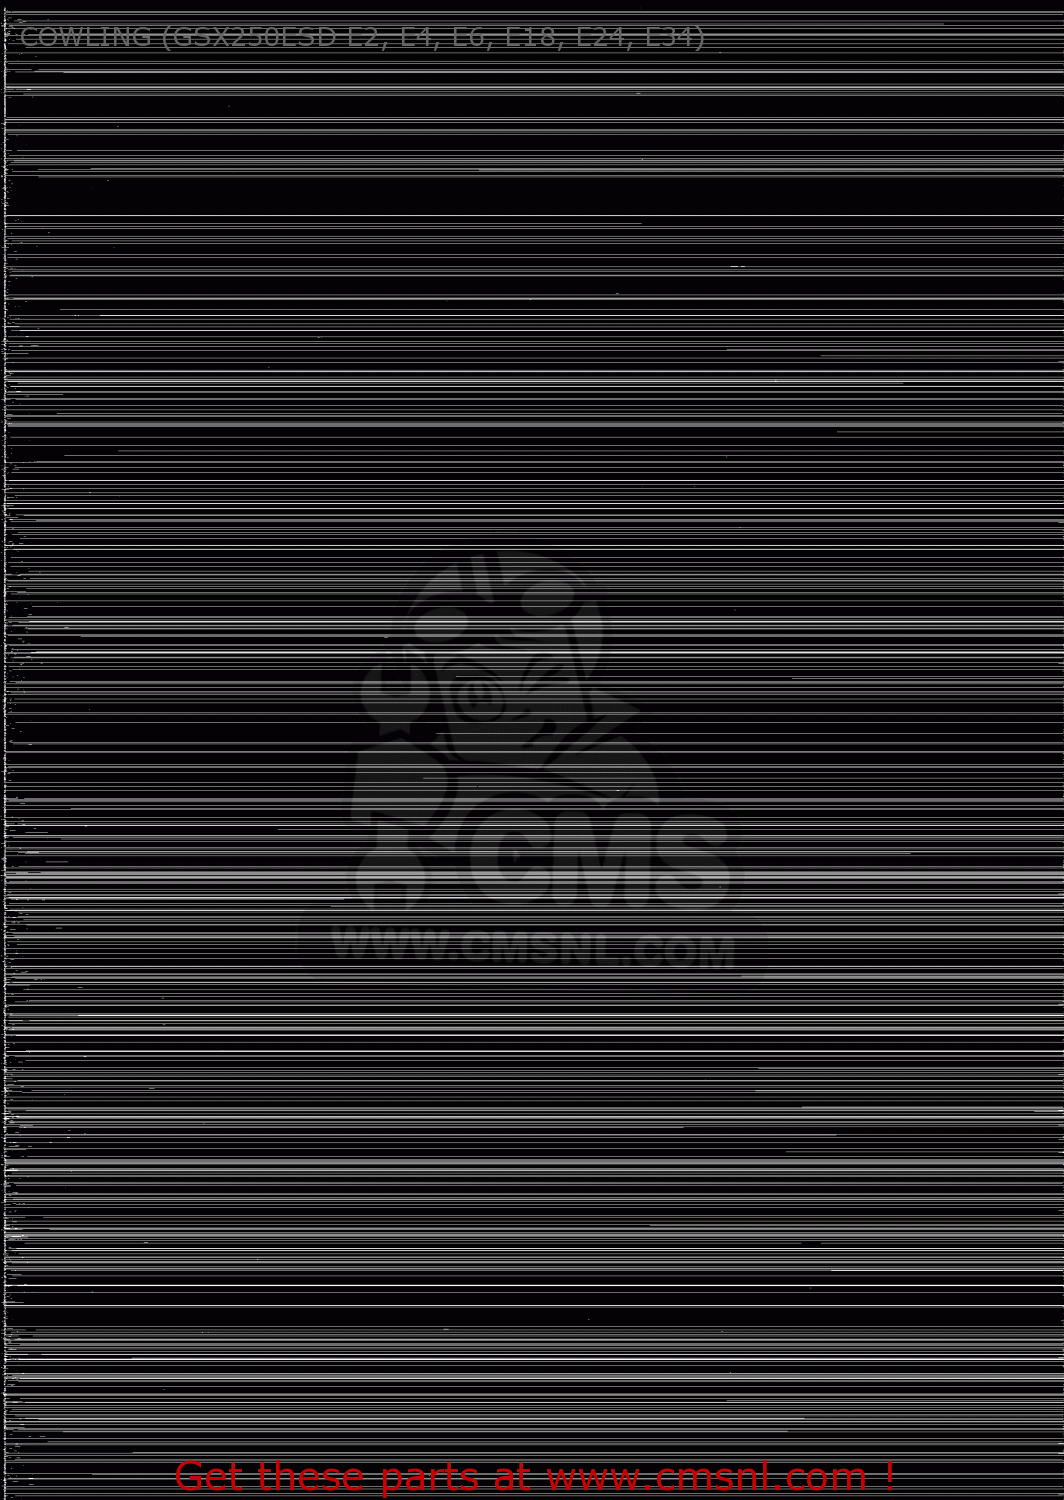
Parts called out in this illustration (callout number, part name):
1	COWLING ASSY (SILVER/RED)
2	COWLING ASSY
3	WINDOW
4	MOULDING
5	CUSHION
6	SCREW M5X12 DIN 7985/N
7	WASHER,5MM
8	NUT
9	MOLDING,HEADLAMP GRILL
10	BRACKET,COWLING RH
11	BRACKET,COWLING LH
12	BOLT
13	LOCK WASHER
14	BRACKET, FITTING RH
15	BRACKET, FITTING LH
16	BOLT, UPPER
17	WASHER (6.5X18X1.6)
18	BRACKET, LOWER
19	BOLT
20	LOCK WASHER
21	WASHER
22	TAPE SET
